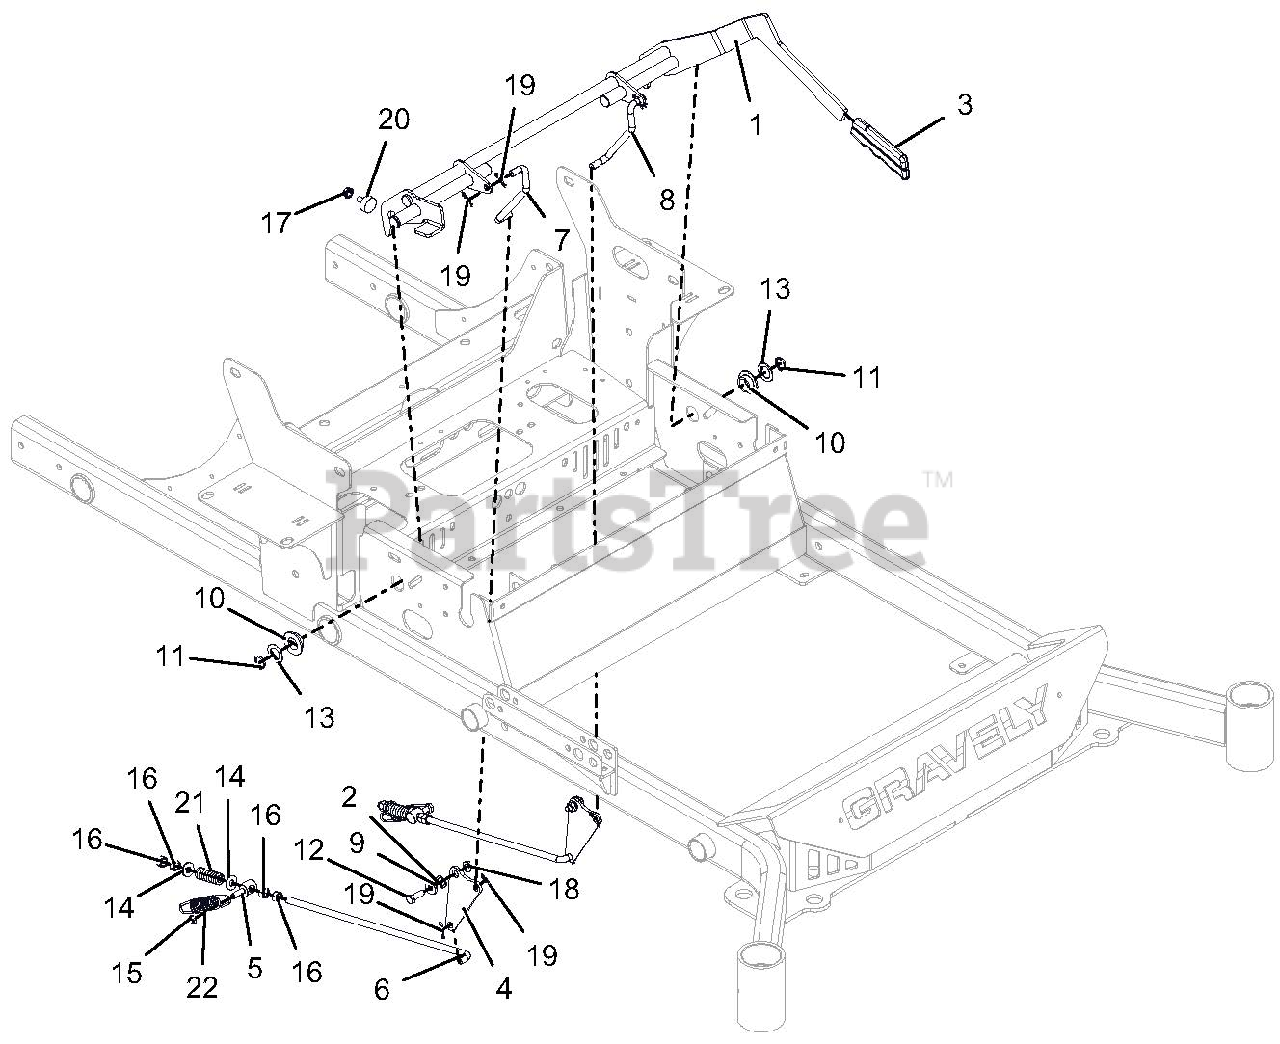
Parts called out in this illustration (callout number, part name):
1	WLDMT,PT200/400 PARK BRAKE-GAS
2	WAVE WASHER .531X.781X.125FH
3	GRIP, PARKING BRAKE (YELLOW)
4	PLATE, BRAKE PIVOT
5	TRUNNION, .38-16
6	ROD, BRAKE ADJ.
7	LINKAGE, RH BRAKE ACTUATING
8	LINKAGE, LH BRAKE ACTUATING
9	BSHG-FLG .32X.500X.344X.880
10	BSHG-FLG .762X1.48X.44 NYL
11	RG-RTNG-EXT .689X.078
12	@BLT-HEX .31-18X1.00 GR5 YWZC
13	WSHR-HDND-THRST .758X1.23X.031
14	@WSHR-FL-STL.38X.875X.083 YWZC
15	@NUT-LK-CTR-JAM .31-18 YWZC
16	@NUT-HEX .38-16 YWZC
17	@NUT-SPNLK-FLG .312-18 YWZC
18	@NUT-LK-TOP-FLG .31-18 YWZC
19	PIN-HAIR, ENDRIES #25 YWZC
20	BUMPER, RUBBER
21	SG-COMP .142 X .710 X 1.75
22	SPRING-TENS .105X.850X.4.880
